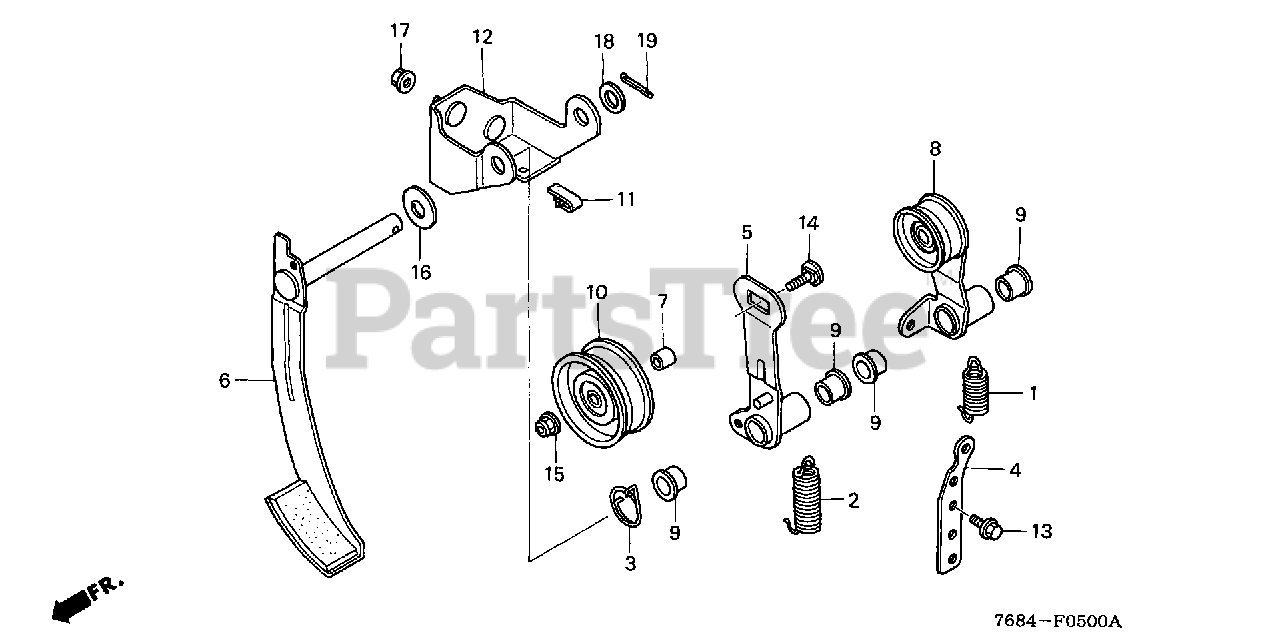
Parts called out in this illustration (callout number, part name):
1	SPRING, WHEEL TENSION RETURN
2	SPRING, AUGER TENSIONER RETURN
3	SPRING, BRAKE ARM
4	STAY, TENSIONER SPRING
5	ARM, AUGER TENSIONER
6	ARM, AUGER BRAKE
7	COLLAR, ROLLER
8	ARM, WHEEL TENSIONER
9	BUSH, TENSIONER ARM
11	RUBBER, STOPPER
12	BRACKET, TENSION ARM
13	BOLT, FLANGE (6X12) (CT200)
14	BOLT, ROLLER
15	NUT, SELF-LOCK (8MM) (CLINCH)
16	WASHER, BRAKE ARM
17	NUT, FLANGE (8MM)
18	WASHER, PLAIN (12MM)
19	PIN, SPLIT (3.0X18)
